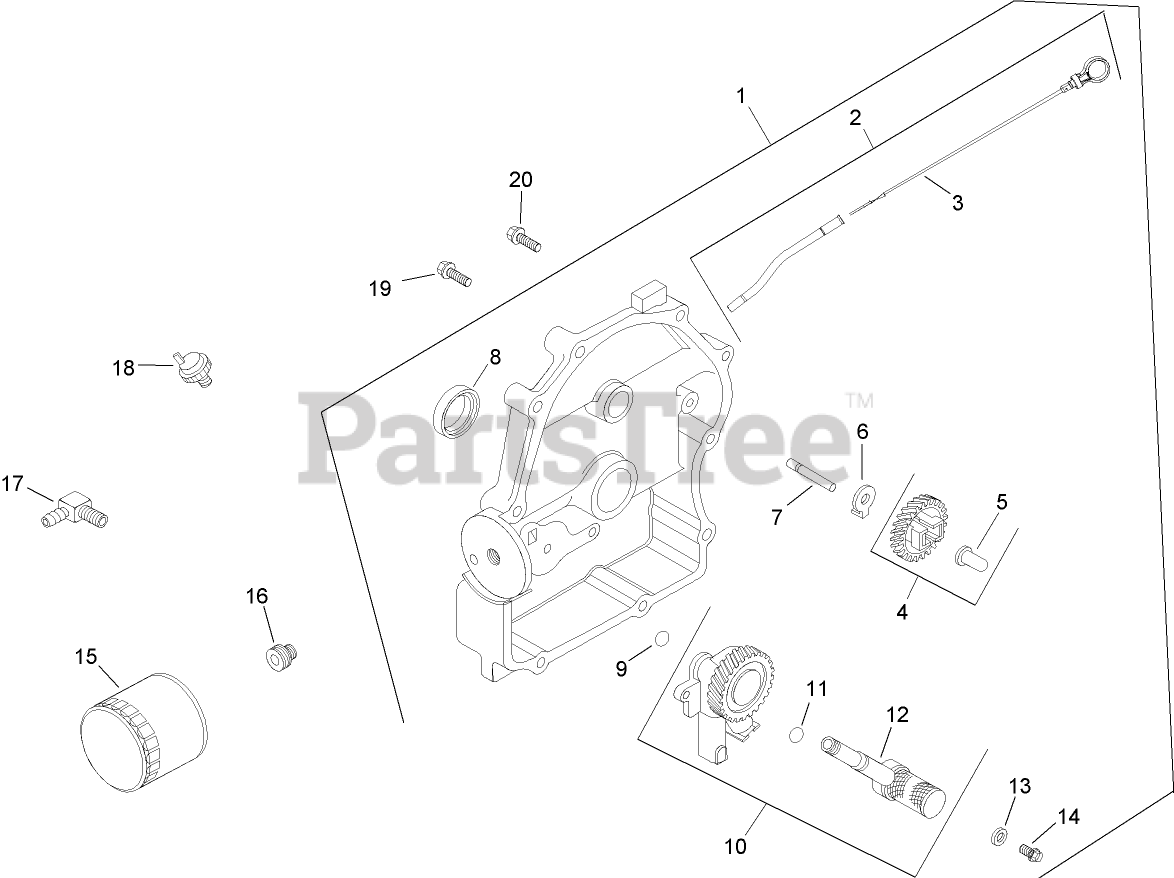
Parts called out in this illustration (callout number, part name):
1	Closure Plate ASM (Includes 2-13)
2	Dipstick Tube ASM (Includes 3)
3	Dipstick
4	Governor Gear Kit (Includes 5)
5	PIN-REGULATING, GOVERNOR
6	TAB-LOCKING
7	SHAFT-GEAR, GOVERNOR
8	SEAL-OIL (P-T-O END)
9	O-Ring
10	Oil Pump ASM (Includes 11, 12)
11	O-RING
12	TUBE-PICK UP, OIL
13	WASHER-FLAT (6 MM)
14	SCREW-FLANGE, THREAD FORMING (M6X1.0X25)
15	Filter-Oil
16	Nipple-Filter, Oil
17	Connector-Hose, 90 Deg
18	SWITCH-PRESSURE, OIL
19	Screw-HF (M8x1.25x45)
20	SCREW-FLANGE (M8X1.25X45)
